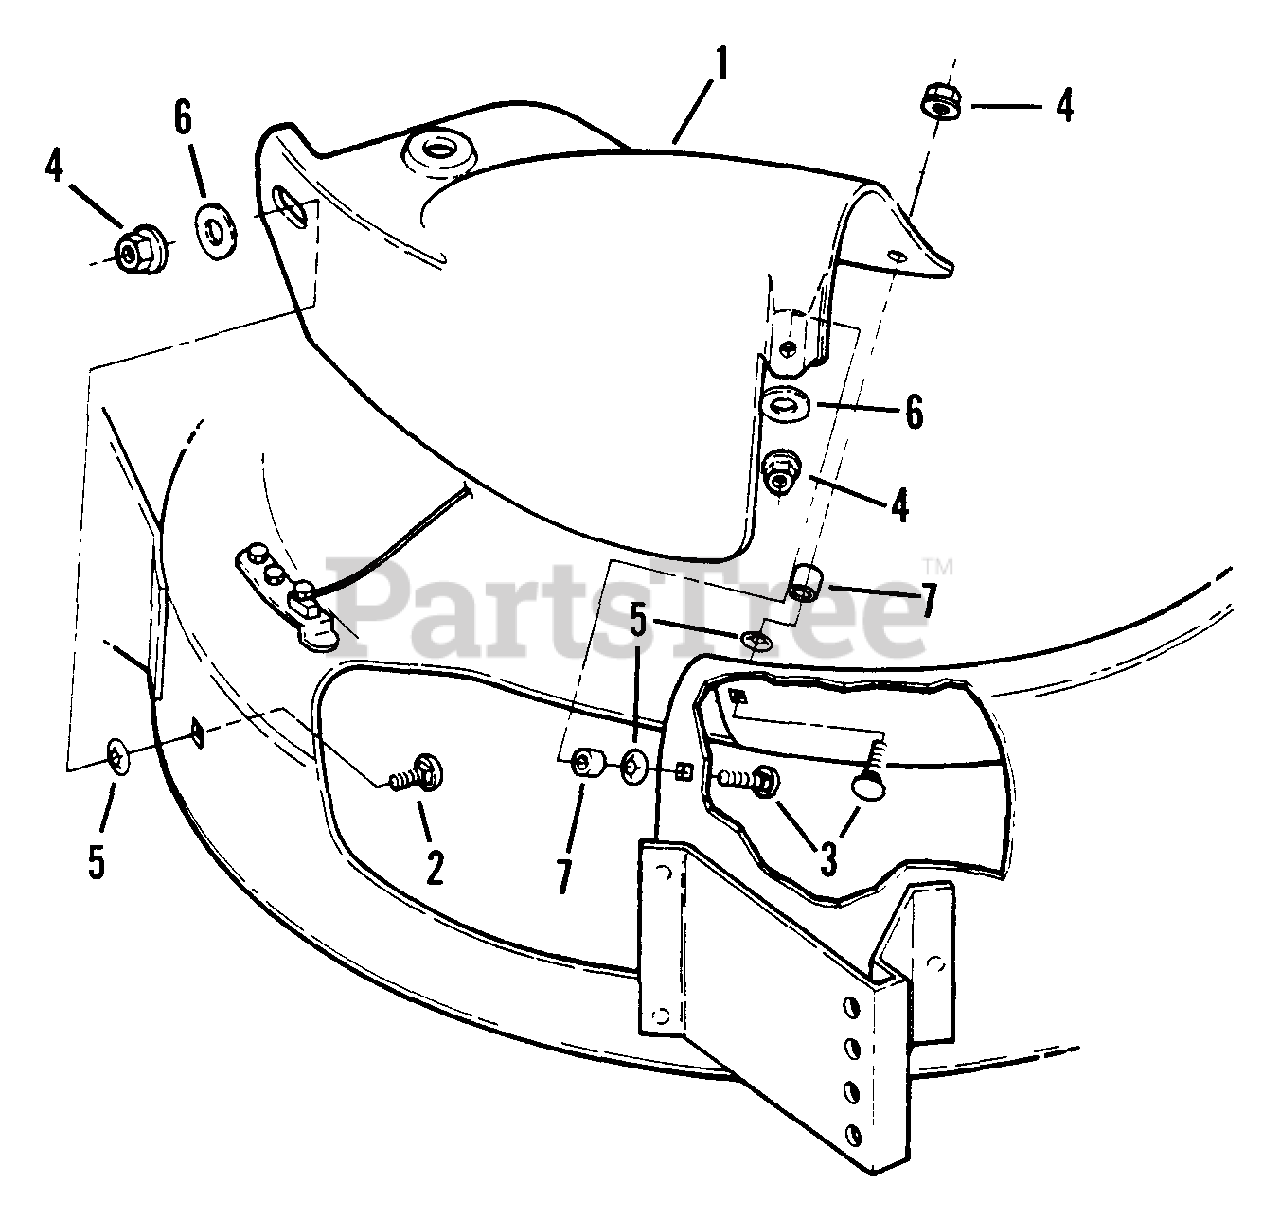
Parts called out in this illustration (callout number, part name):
1	COVER, Recycling
2	BOLT, 5/16-18 x 3/4" Short Neck Carriage
3	BOLT, 5/16-18 x 1" Short Neck Carriage
4	NUT, 5/16-18 Center Lock
5	RETAINER, 5/16 Bolt
6	WASHER, 5/16 Flat
7	SPACER
